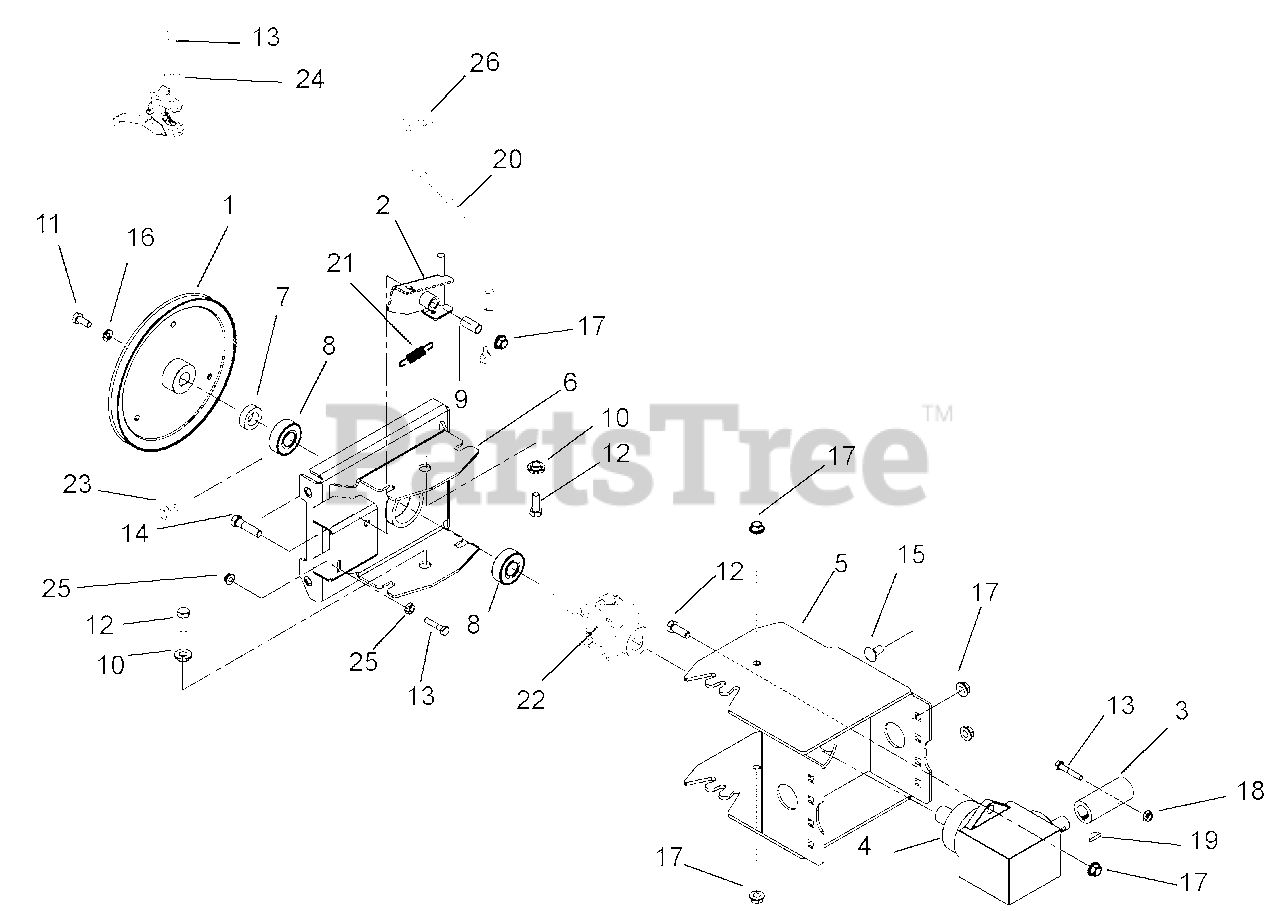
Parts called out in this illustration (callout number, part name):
1	PULLEY, 4L W/HUB, .75 X 8.5
2	ARM, PIVOT LOCK
3	HUB, COUPLING
4	GEAR BOX ASSEMBLY
5	ADAPTER WITH DECAL,BRUSH FRAME
6	ADAPTER, PLATE-32000 SERIES
7	SPACER .755X1.250X.370
8	BRG-BALL .750X1.781X.61
9	BSHG-SLV .385X.500X1.045
10	BSHG-FLG .406X.88X.270X.140
11	BLT-HEX .31-24X.75 YWZC GR5
12	@BLT-HEX .38-16X1.00 GR5 YWZC
13	@BLT-HEX .25-20X1.50 GR5 YWZC
14	@BLT-HEX .38-16X1.75 GR5 YWZC
15	@BLT-RDHDSQNK .38-16X.75 G5YZ
16	WSHR-LK .312X.097 HVY YWZC
17	@NUT-LK-TOP-FLG .38-16 YWZC
18	@NUT-LK-TOP-FLG .25-20 YWZC
19	KEY-WDRF .188X.75X.313 SAE 9
20	CABLE, REMOTE BRUSH LOCK
21	SG-TENS .06X.46X2.00
22	U-JOINT ASSY
23	@SCR-TAP .38-16X.75 HWH TR YWZ
24	SPACER, HANDLEBAR
25	@NUT-SPNLK-FLG .25-20 YWZC
26	J-CLAMP
